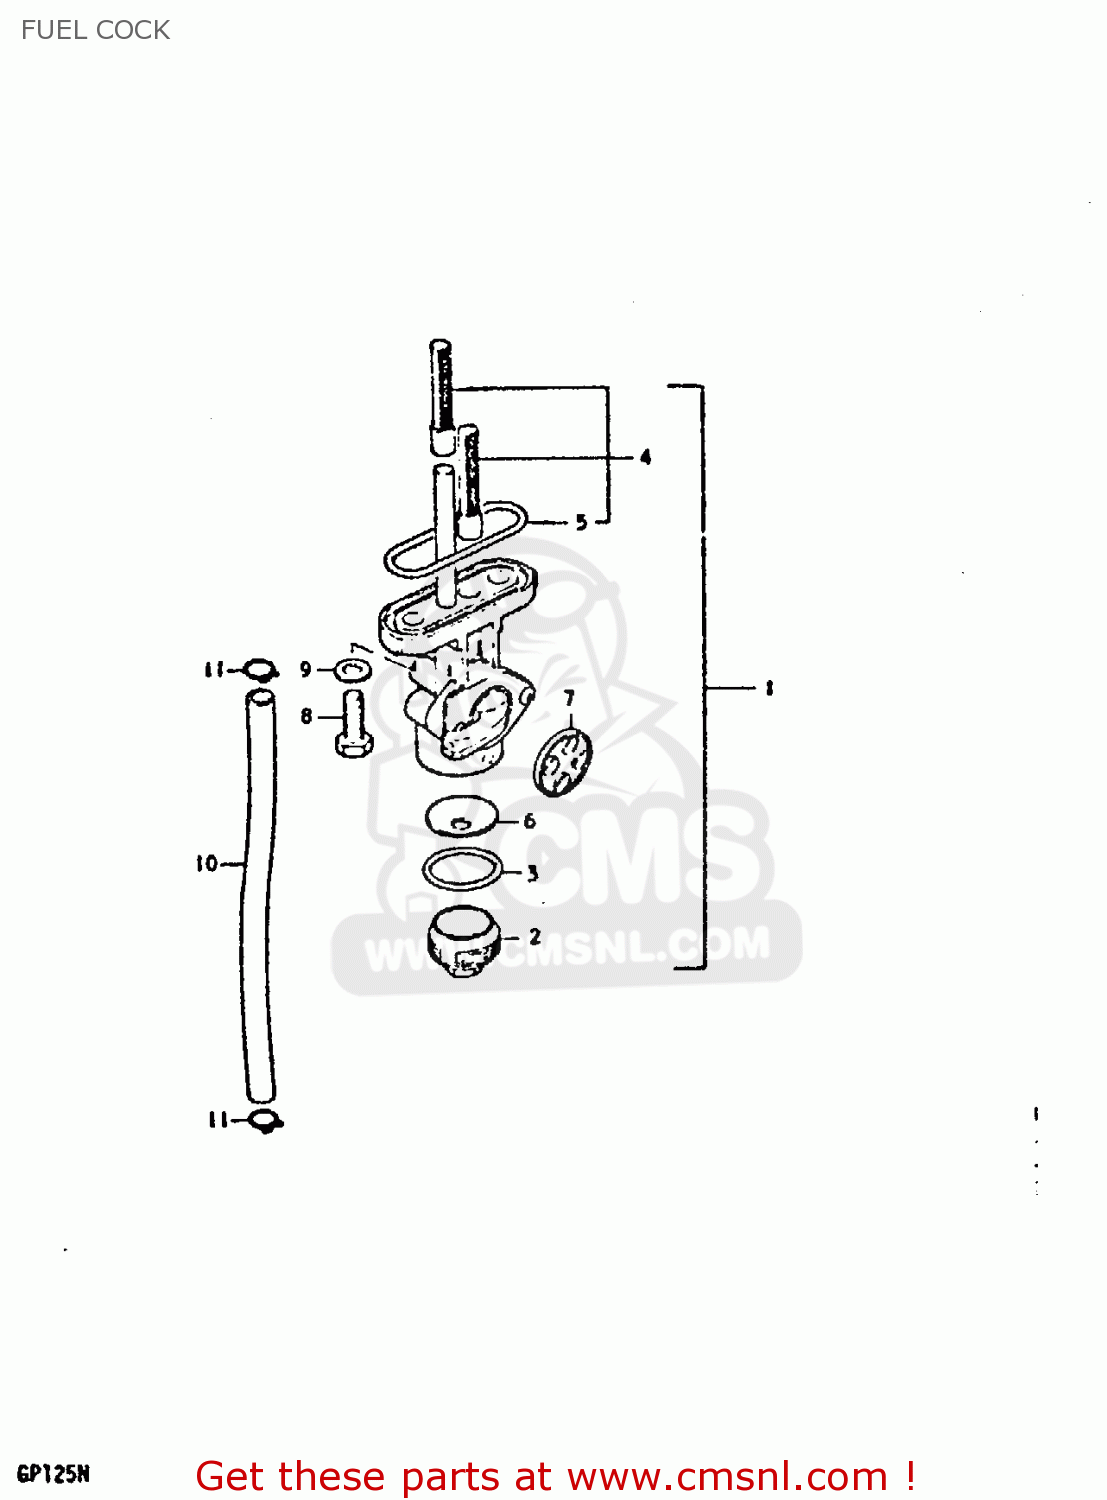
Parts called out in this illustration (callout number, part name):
1	COCK ASSEMBLY,FUEL
2	CUP,FUEL COCK
3	GASKET,FILTER (NAS)
4	FILTER SET,FUEL COCK
5	O RING,FUEL COCK
6	NET,STRAINER
7	GASKET,LEVER (NAS)
8	BOLT L:16
9	GASKET
10	HOSE
11	CLIP
